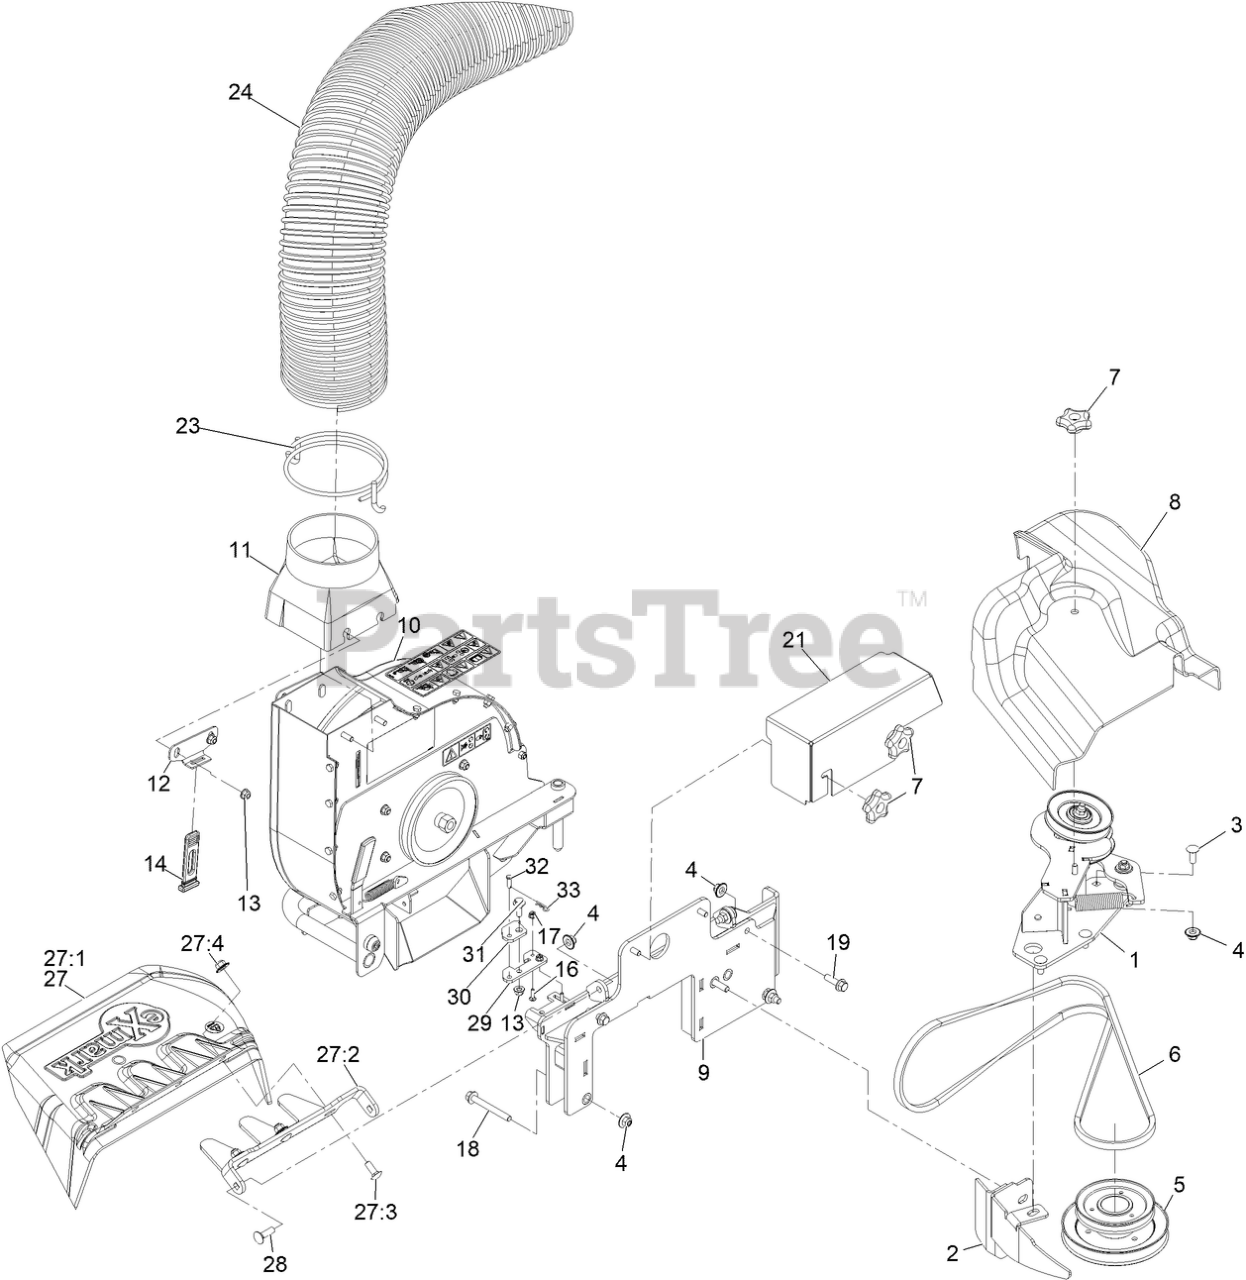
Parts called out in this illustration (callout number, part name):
1	ASM-BLOWER IDLER
2	BAFFLE-DOGLEG
3	SCREW-CARR
4	Nut-Nyloc 3/8-16 Flg
5	JACKSHAFT, UV DRIVE 604 SPLINED
7	KNOB-HANDLE
8	COVER-BELT
9	MOUNT ASM-BLOWER
10	BLOWER ASM
11	TRANSITION
13	NUT-HF, NI
14	STRAP-DOWN, HOLD
16	SCREW-CARR
18	Screw-HHF
19	SCREW-HHF
21	Guard-Belt, Blower
23	CLAMP-HOSE, BAGGER
24	HOSE-FLEXIBLE
27	ASM,DISCHARGE CHUTE
27:1	CHUTE,DISCHARGE
27:2	BRACKET,DISCHARGE CHUTE
27:3	SCREW-CARR
27:4	Nut-Nyloc 3/8-16 Flg
28	BOLT-CARR
29	Catch-Blower Latch
30	Lock Bar-Blower Latch
31	SCREW-SHOULDER
32	PIN-CLEVIS
